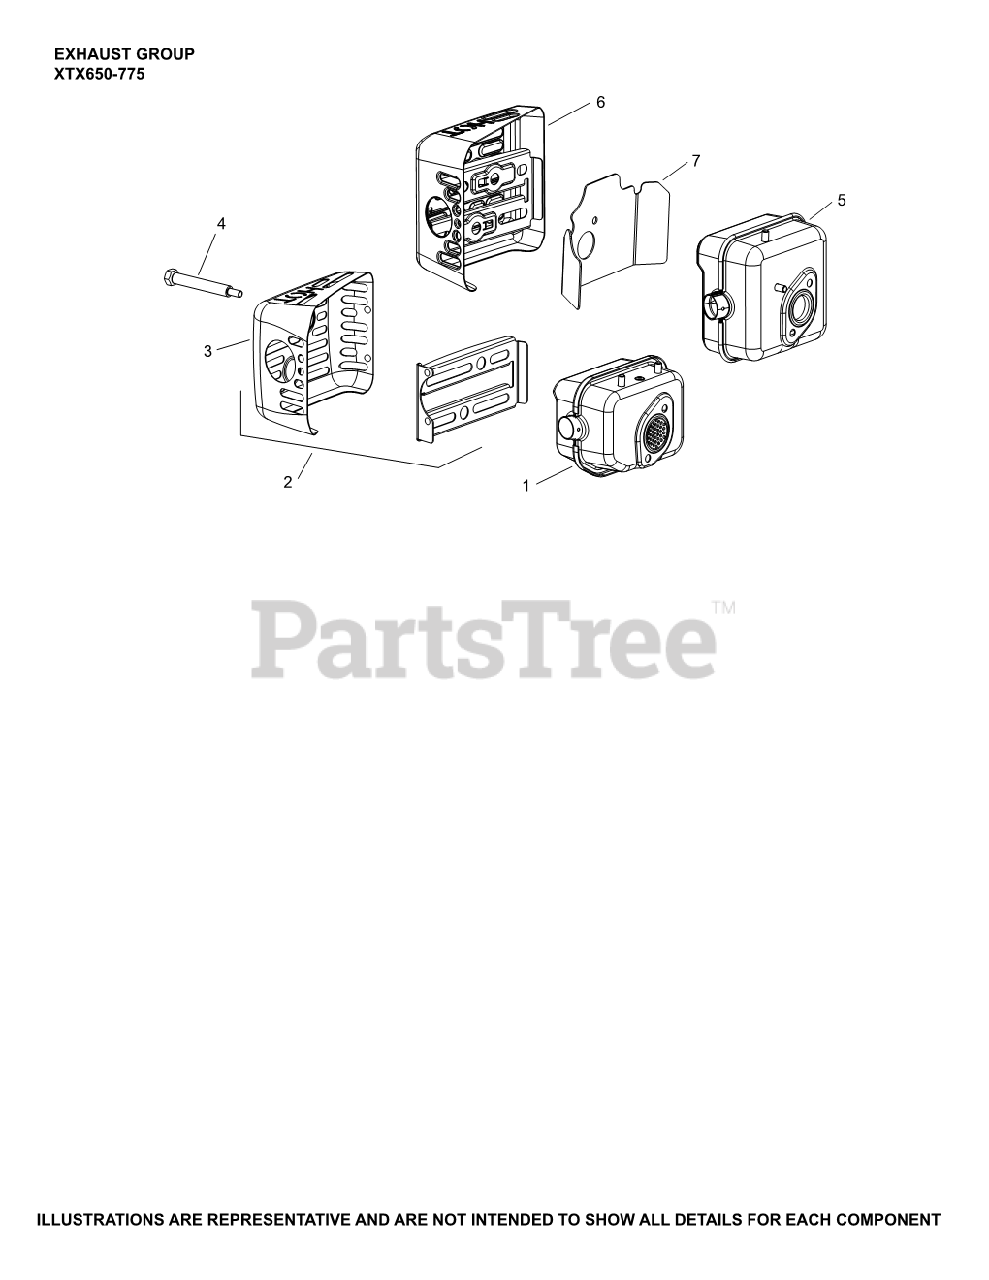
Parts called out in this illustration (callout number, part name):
1	KIT, MUFFLER
2	GUARD, MUFFLER
7	GASKET, MUFFLER
